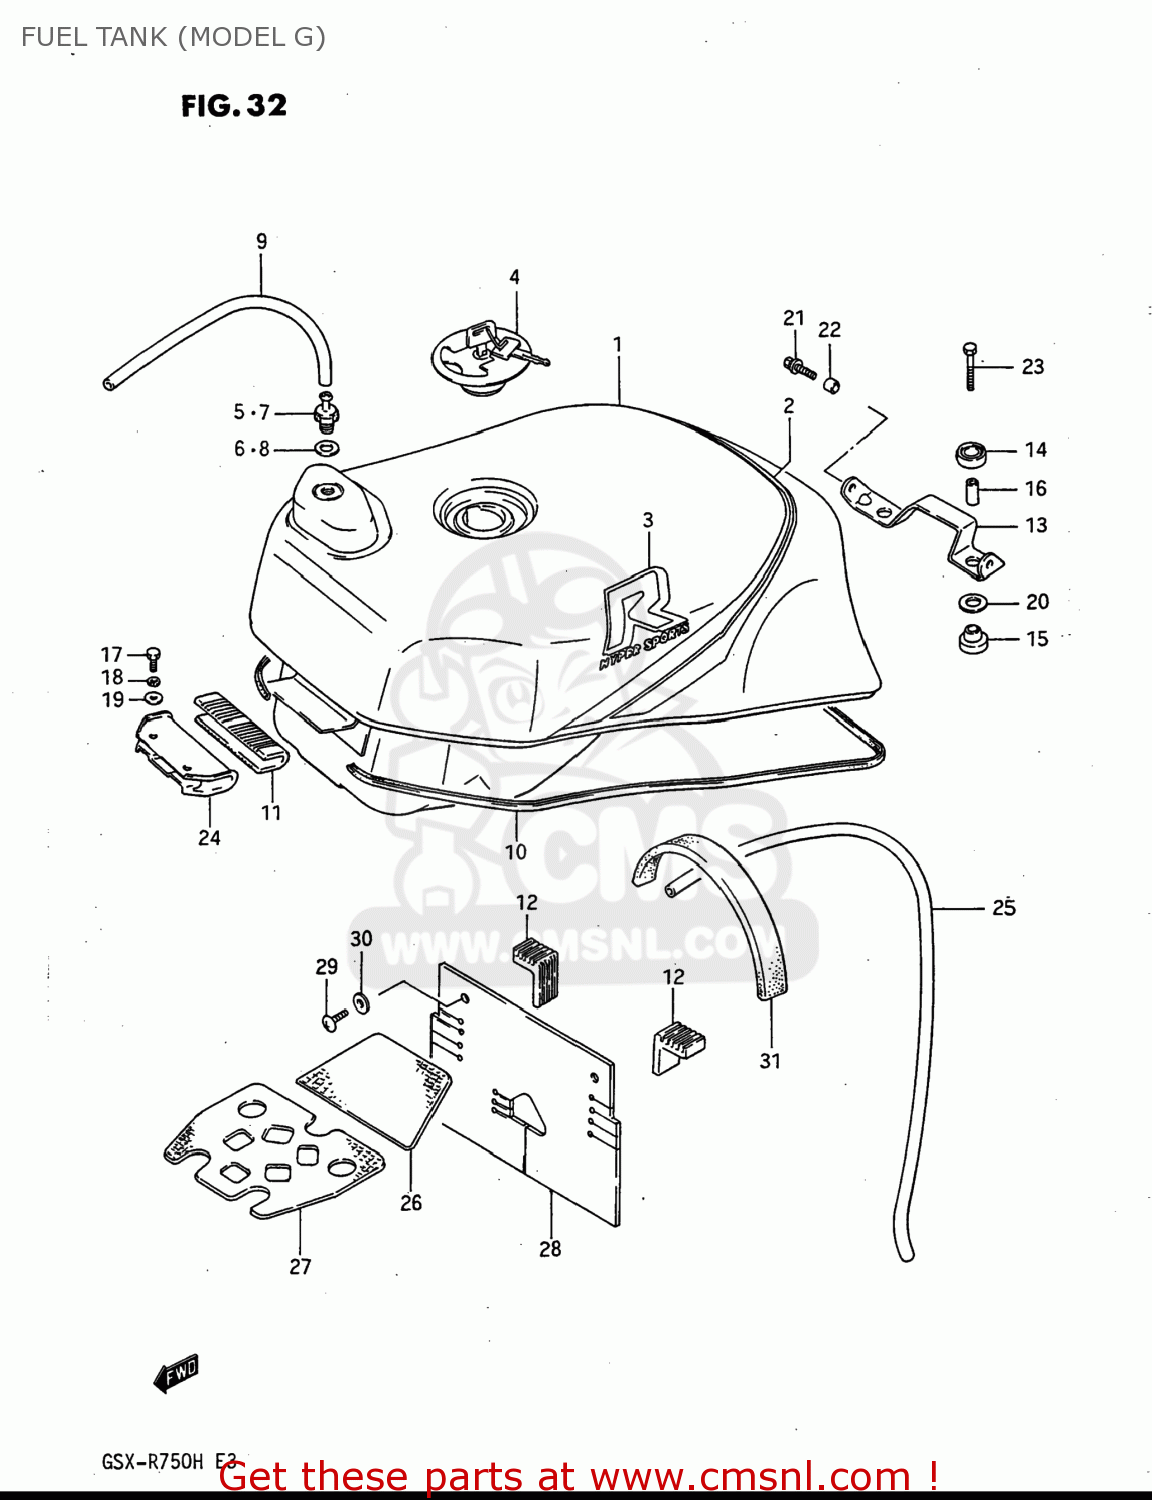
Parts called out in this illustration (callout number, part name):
1	TANK ASSEMBLY,FUEL
2	TAPE SET,FUEL TANK
3	EMBLEM
4	CAP SET,FUEL TANK
5	PLUG, FUEL TANK BREATHER
6	GASKET(12.5X20X2.5) (NAS)
7	(CA) VALVE,FUEL TANK BREATHER
8	GASKET 27X40X2.5 (NAS)
9	HOSE,FUEL
10	MOLDING,FUEL TANK
11	CUSHION,FUEL TANK FR
12	CUSHION,FUEL TANK SIDE
13	BRACKET,SEAT SUPPORT,FRONT
14	CUSHION
15	CUSHION
16	SPACER
17	BOLT
18	WASHER,LOCK
19	WASHER
20	WASHER (6.5X24X1.6)
21	BOLT ,6X35
22	WASHER (12.5X24X1.6)
23	SCREW(6X16)
24	BRACKET,FUEL TANK FR
25	HOSE,FUEL
26	SHIELD,FUEL TANK HEAT
27	SHIELD,FUEL TANK HEAT
28	SHIELD,HEAT NO.1
29	SCREW
30	WASHER
31	SHIELD,TANK & CLEANER
